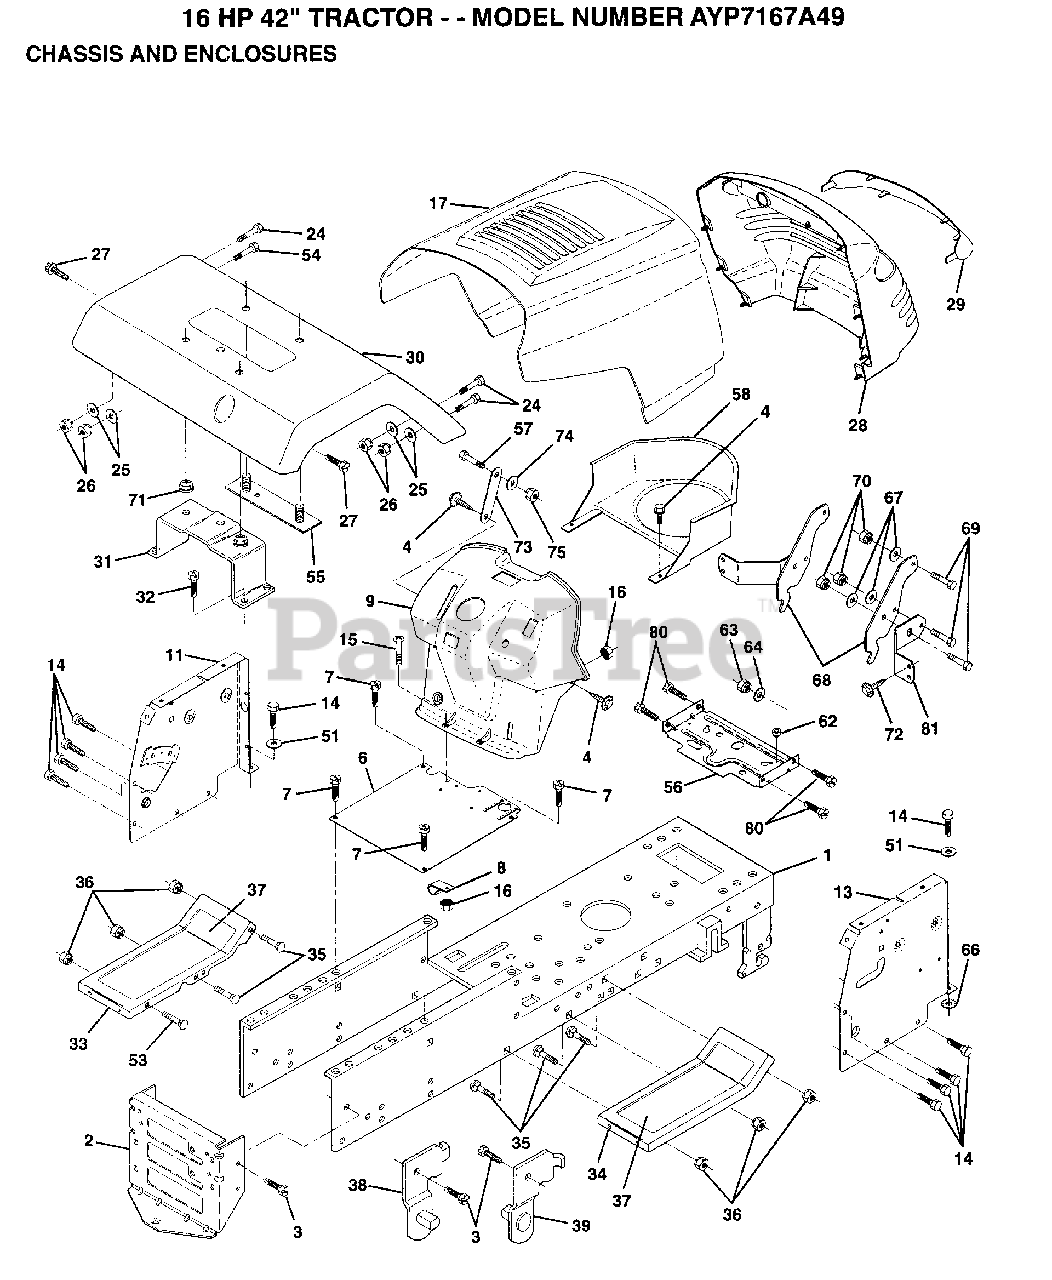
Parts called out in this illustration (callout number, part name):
3	SCREW
4	SCREW HEX CRT
7	SCREW
8	CLIP T
11	PANEL ASM DASH
14	SCREW LT
15	SCREW
16	NUT
25	WASHER
27	SCREW LT
29	LENS GRILLE
30	FENDER.PNT.
31	BRKT.ASM.FENDER
32	SCREW
35	BOLT
37	FOOTREST PAD
38	BRACKET ASM LH
39	BRACKET ASM RH
51	WASHER
55	STRAP ASM FENDER
59	PAD IDLER TI
64	LOCKWASHER.5/16.E
66	LOCKWASHER
67	WASHER
68	HING PICK-OFF HD
69	BOLT LT
71	NUT-PUSH YT
73	BRACE SUPT DASH
74	WASHER
75	NUT
80	SCREW TI
81	BRACKET GRILLE
